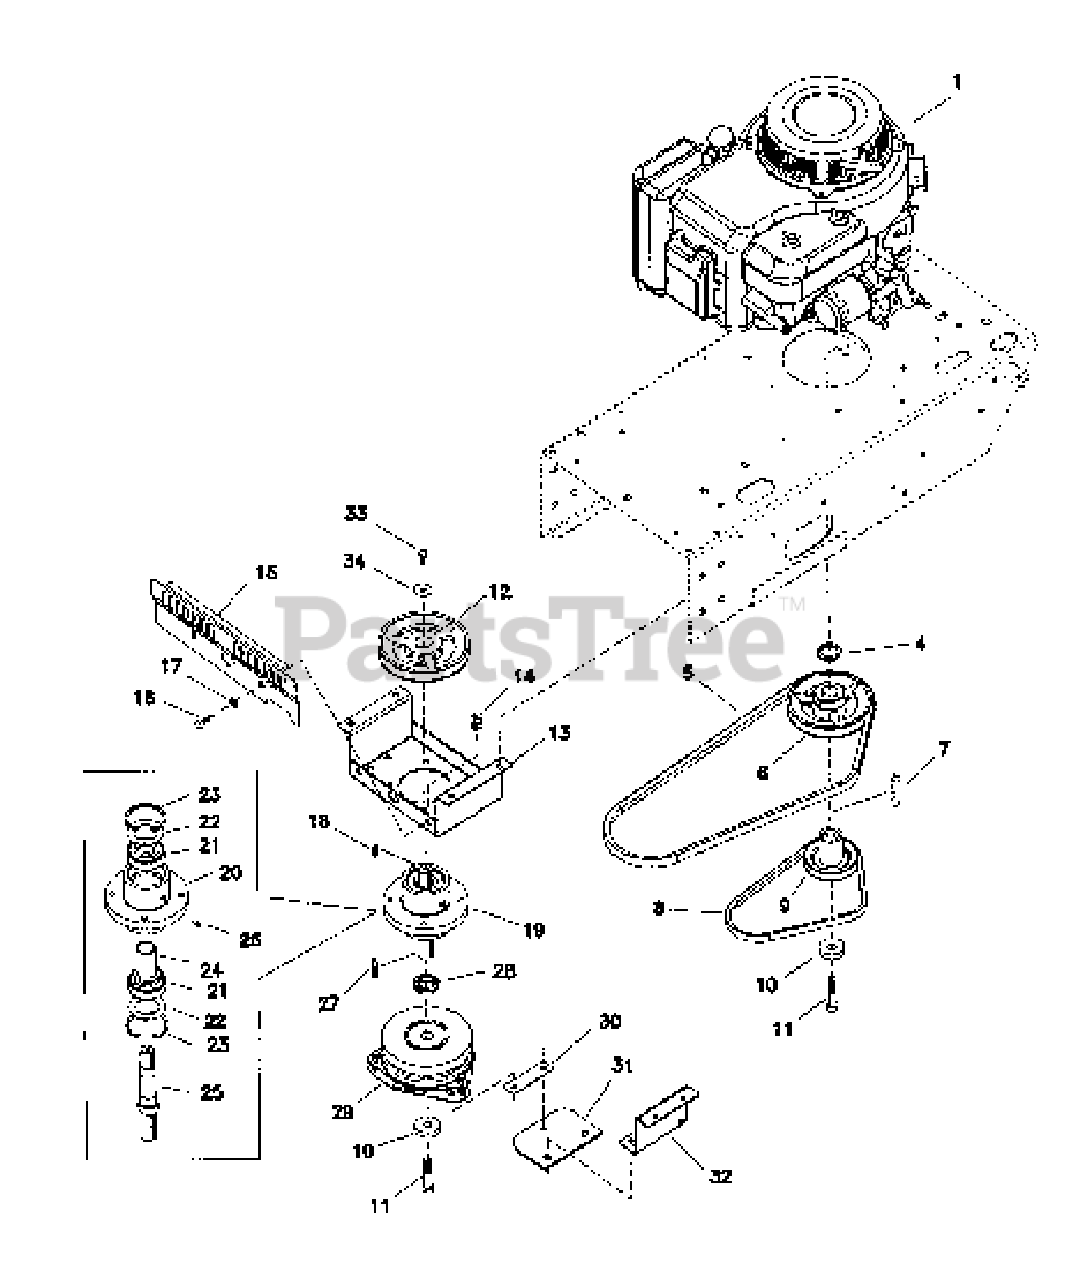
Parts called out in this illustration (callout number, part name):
1	* ENGINE, 14HP Kohler Electric Start
4	SPACER, Crankshaft
5	BELT (Jackshaft)
6	PULLEY
7	KEY, 1/4 x 2-1/2
8	BELT (Transmission)
9	PULLEY, Transmission Drive
10	RETAINER, Clutch
11	CRANKSHAFT BOLT
12	PULLEY, Jackshaft Spindle
13	JACKSHAFT MOUNT
14	BODY CLIP, 5/16-18
15	JACKSHAFT GUARD
16	CAPSCREW, Hex Head, 5/16-18 x 3/4
17	WASHER, 5/16
18	KEY, 3/16 x 1
19	JACKSHAFT SPINDLE ASSEMBLY, Complete (Includes Ref 20-26)
20	HOUSING
21	BEARING
23	SNAP RING
24	BEARING SPACER
25	JACKSHAFT
26	GREASE FITTING
27	KEY, 1/4 x 1
28	CLUTCH SPACER
29	CLUTCH, Electric PTO
30	STRAP
31	PAD, Clutch Anchor
32	CLUTCH ANCHOR
33	CAPSCREW, Hex Head, 5/16-24 x 3/4
